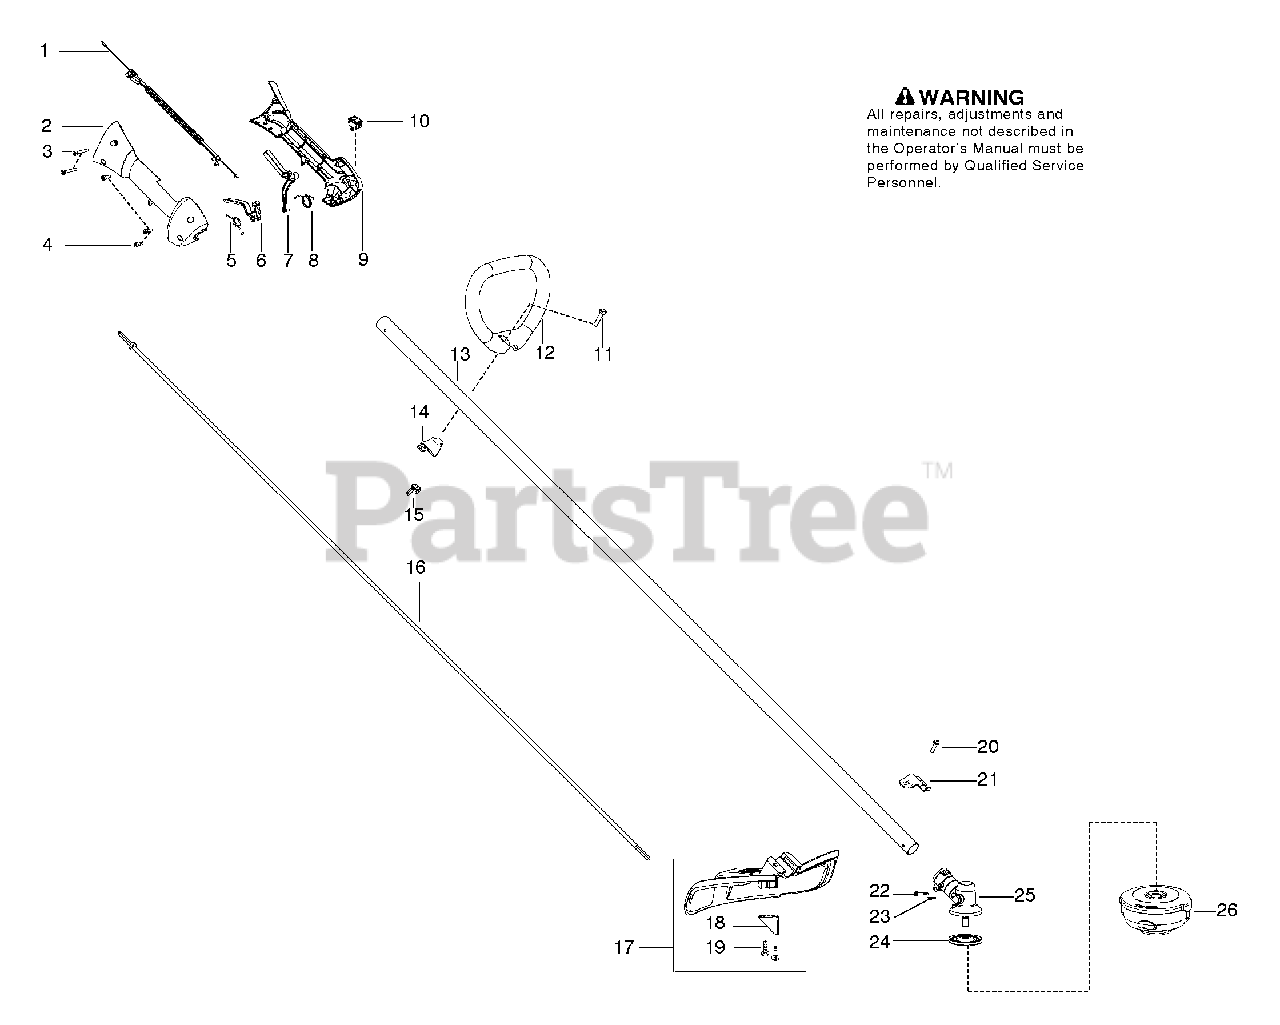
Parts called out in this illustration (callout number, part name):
1	Assy-Cable/Wire Harness
2	Housing-Throttle (RH)
5	Spring-Trigger
6	Trigger
7	Lockout-Throttle
8	Spring-Lockout
9	Housing-Throttle (LH)
10	Kit-Switch
12	Handle-Assist
13	Kit-Driveshaft SST
14	Clamp-Handle
15	Wingnut
16	Flex shaft
17	Kit-Shield
18	Limiter-Line
21	Bracket-Shield
24	Assy-Dust cup
25	Assy-Gearbox
26	Assy-T25 Cutting Head
